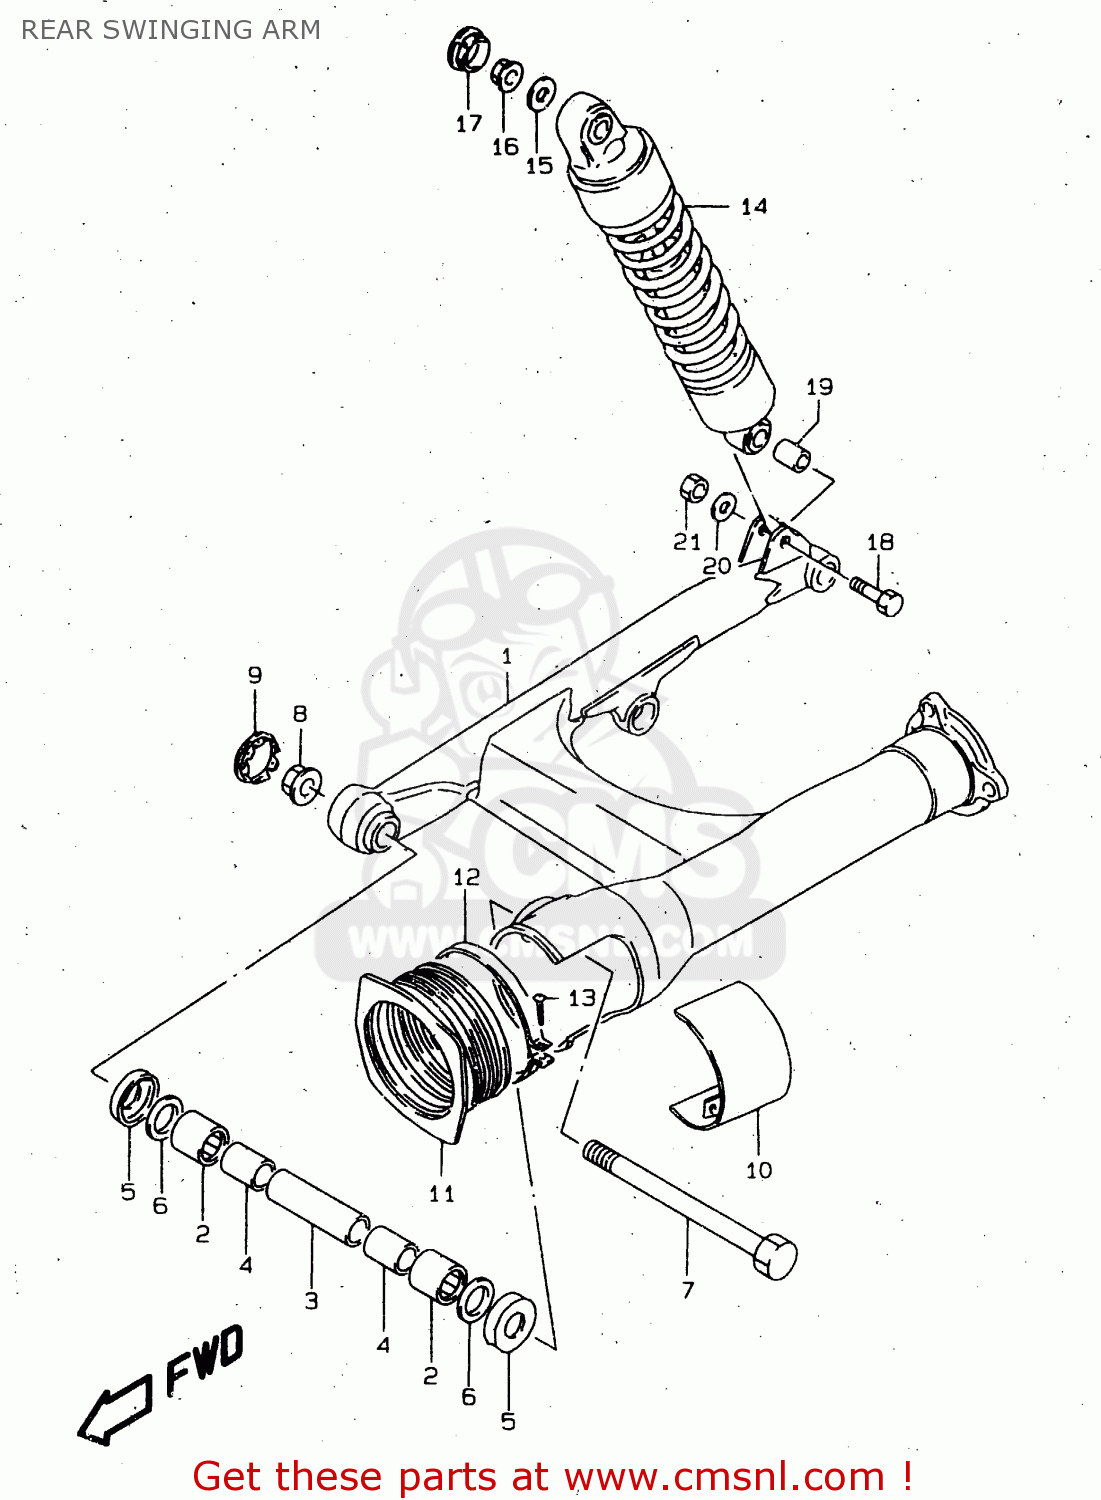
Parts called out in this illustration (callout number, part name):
1	SWINGINGARM,RR
2	BEARING(22X29X30)
3	SPACER,RR SWGARM PIVOT CTR
4	SPACER,RR SWGARM PIVOT
5	SEAL,RR SWGARM PIVOT DUST
6	WASHER
7	SHAFT,RR SWINGINGARM PIVOT
8	NUT
9	CAP,RR SWINGING ARM PIVOT,R
10	COVER,RR SWGARM PIVOT,L
11	BOOT,PROPELLER SHAFT
12	CLAMP
13	SCREW
14	ABSORBER ASSY,RR SHOCK
15	WASHER(10.5X20X2.3)
16	NUT
17	CAP,FRAME HANDLE GRIP
18	BOLT(10X39)
19	SPACER(10.2X14X20.7)
20	WASHER (10.5X24X2.3)
21	NUT
